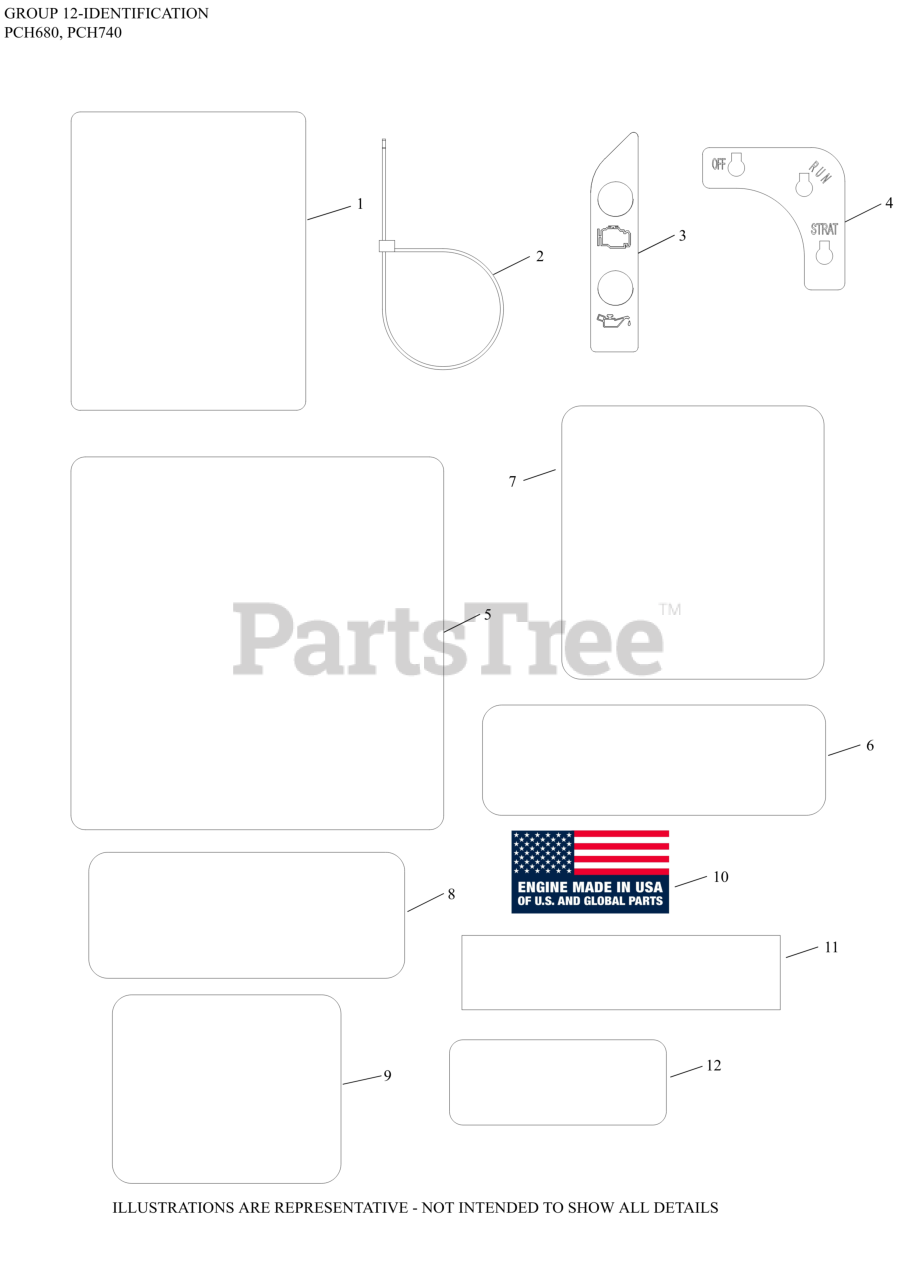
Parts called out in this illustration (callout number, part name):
1	LABEL, CLEAR LAMINATION
3	DECAL, WARNING LIGHT
4	DECAL, KEY SWITCH
6	DECAL LPAC, 23 HP/747cc/PCH680
8	DECAL, SYNTHETIC OIL
